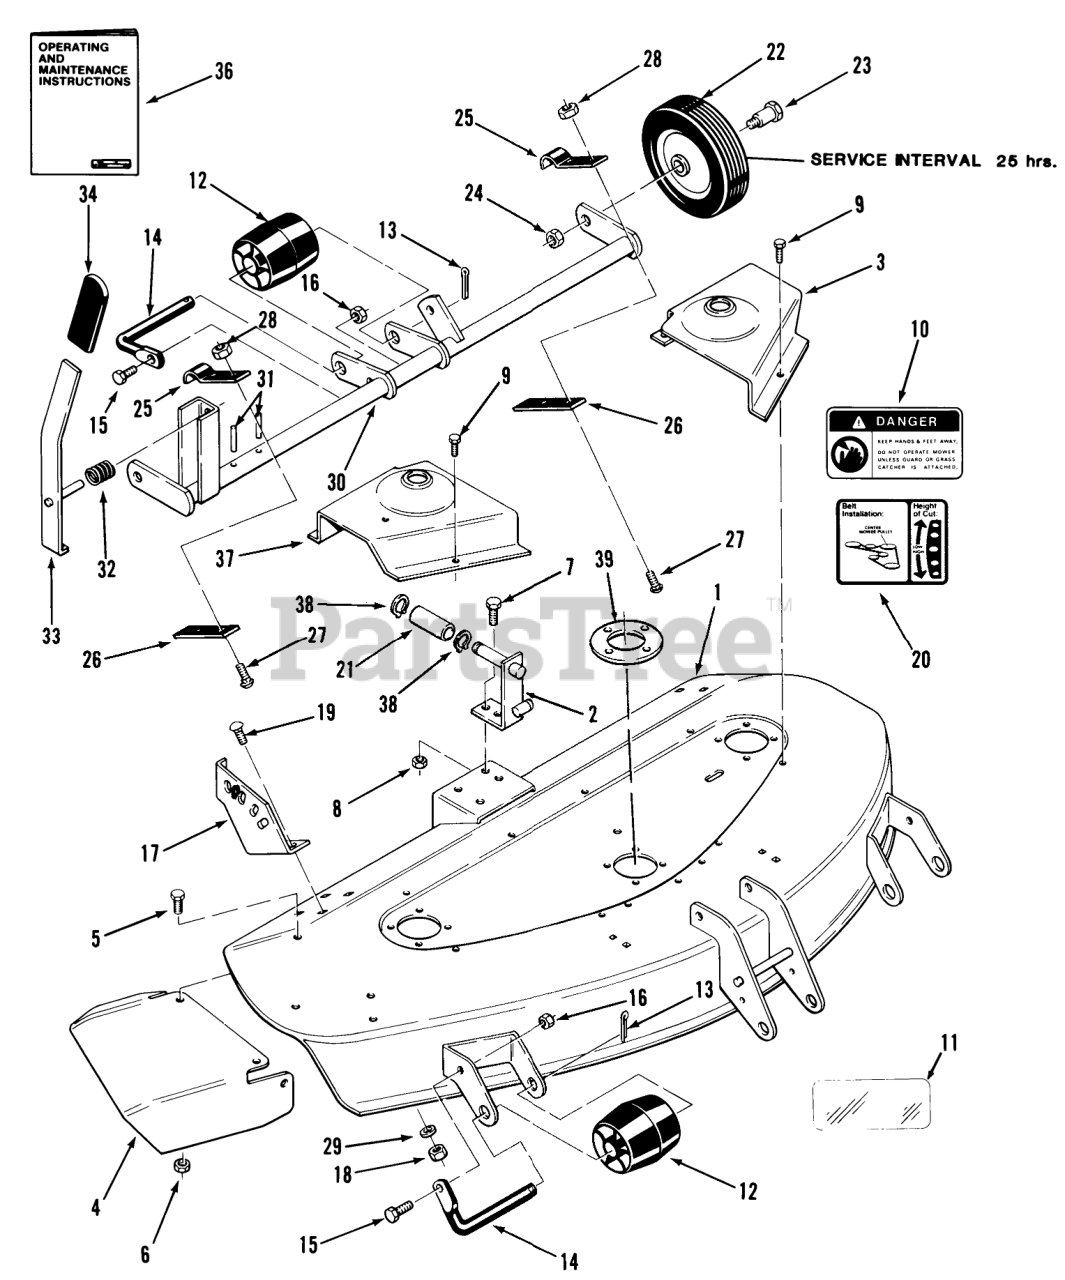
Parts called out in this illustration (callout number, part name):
1	ASSY-DECK 42" MWR R
2	ASSY-GUIDE BRKT-4 R
3	COVER-BELT LH R
4	Chute Extension
5	Bolt
6	Nut
7	BOLT
8	NUT
9	SCREW -4
10	Danger Decal
11	DECAL-OVERLAY
12	Roller
13	Cotter Pin
14	ROLLER-SHAFT
15	Bolt
16	Nut
17	Quadrant
18	NUT
19	Bolt
20	DECAL-HEIGHT BELT
21	SPACER
22	WHEEL
23	BOLT-SHOULDER
24	NUT
25	Clamp
26	Bar
27	Bolt
28	NUT
29	Washer
30	Gage Wheel Support
31	PIN-SPIROL
32	SPRING-COMPRESSION
33	LEVER ASSY R
36	Owner-s & Maintenance Instructions
37	COVER-BELT RH R
38	Snap Ring
39	PLATE-SPINDLE
